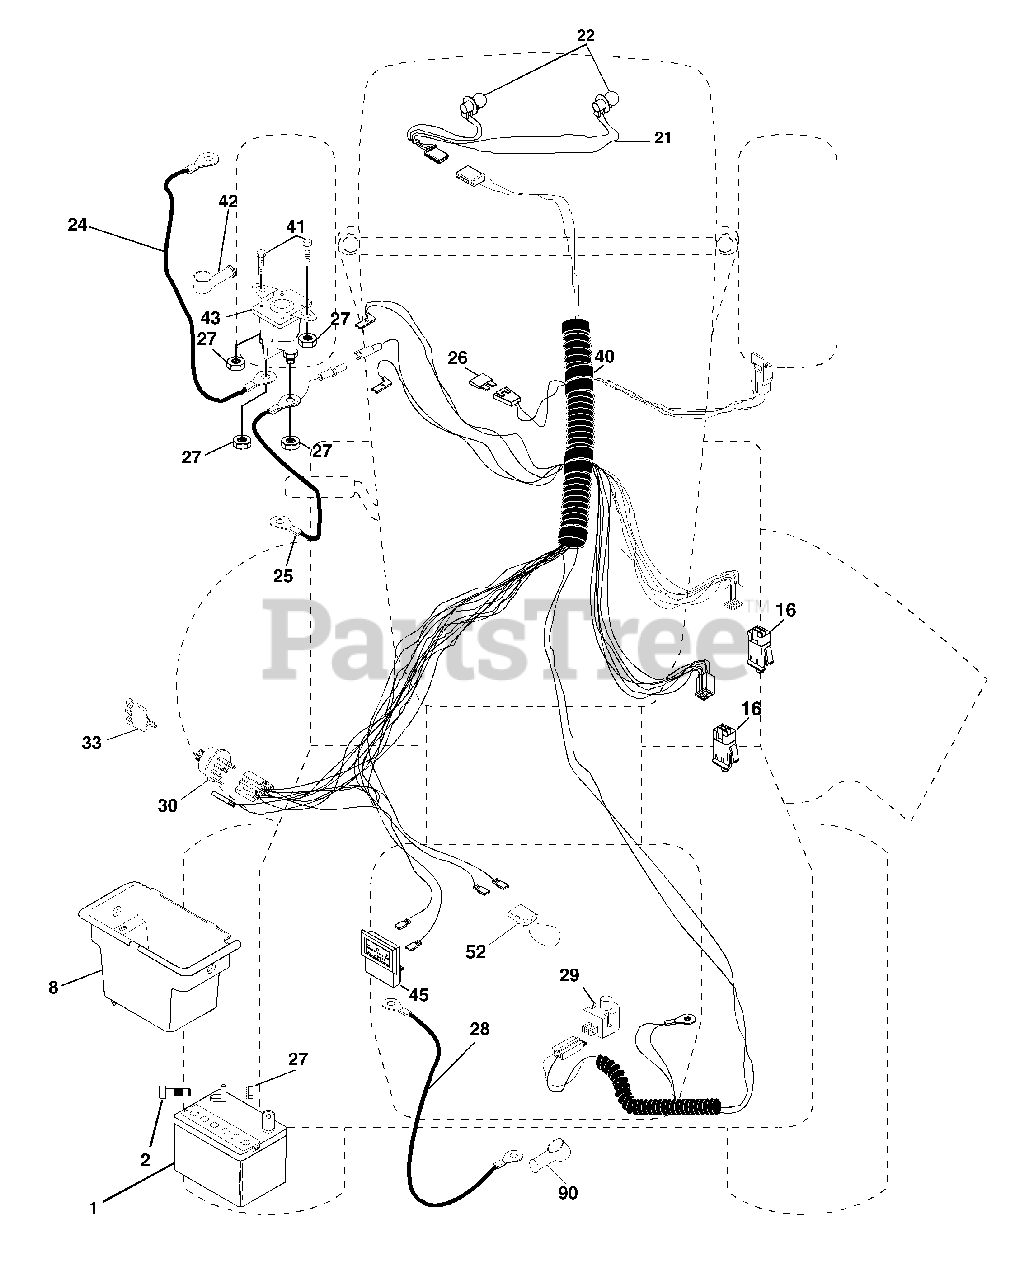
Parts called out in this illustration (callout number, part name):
1	Battery
2	Bolt Hex Hd 1/4-20unc X 3/4
8	Box Battery Fender
16	Switch Interlock
21	Harness Socket Light with 415J
22	Bulb, Light # 1156
24	Cable Battery
25	Cable Battery 6 Ga Red w/16 wire
26	Fuse 20 Amp
27	Nut Keps Hex 1/4-20 Unc
28	Cable Ground 6ga 12 black
29	Switch Plunger Nc Gray
30	Switch Ign
33	Key Ign Molded Generic
40	Harness Ign
41	Bolt Fin Hex 1/4-20uncx 1/2
42	Cover Terminal Red
43	Solenoid
45	Ammeter Rectangular
52	Protection Loop
90	Cover Terminal Battery
